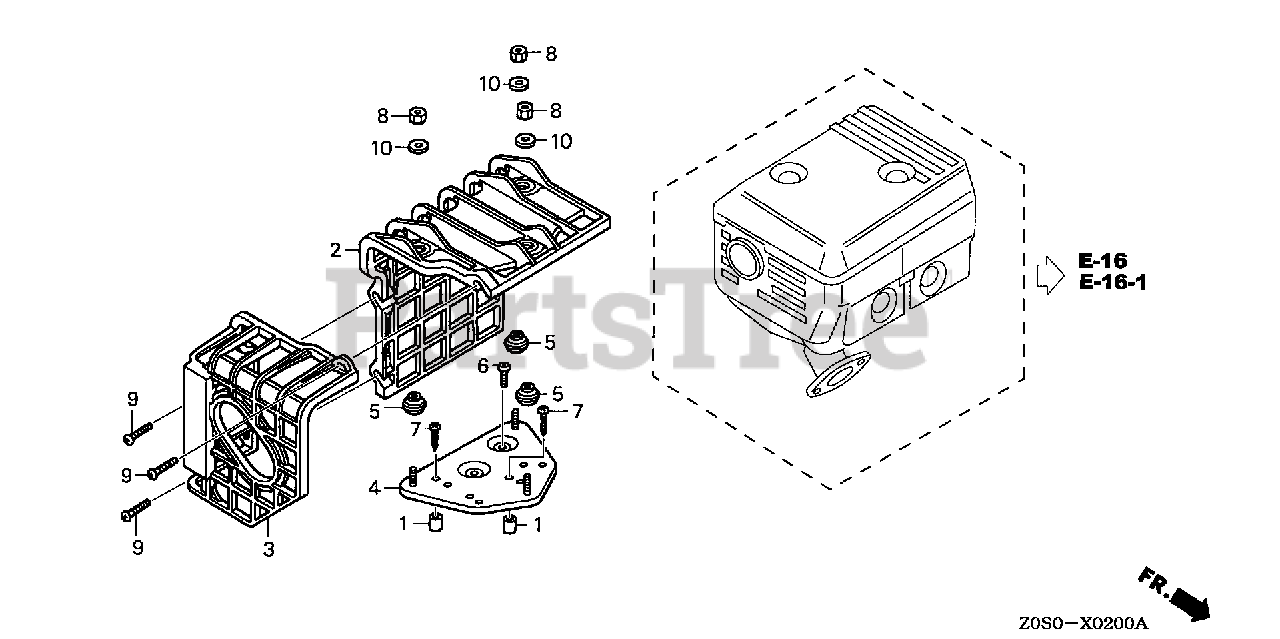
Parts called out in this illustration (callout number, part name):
1	COLLAR, AIR CLEANER HOUSING
2	COVER, MUFFLER
3	COVER, RR. MUFFLER
4	BASE, MUFFLER COVER
5	SPACER, MUFFLER COVER
6	SCREW, TAPPING (5X8)
7	SCREW, TAPPING (5X25)
8	NUT, HEX. (5MM)
9	SCREW-WASHER (6X20)
10	WASHER, PLAIN (5MM)
